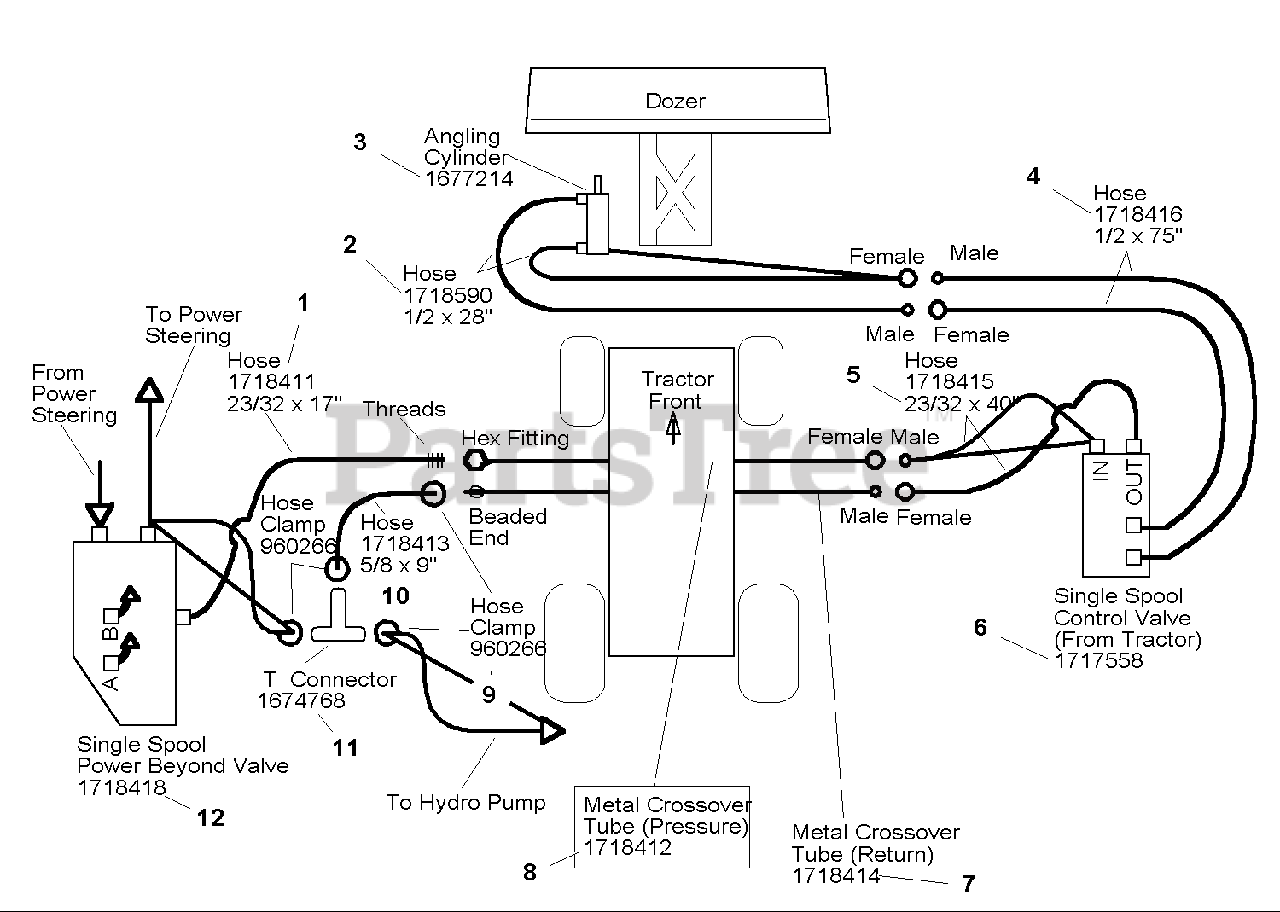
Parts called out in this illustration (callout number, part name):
1	HOSE ASSEMBLY, 23/32" x 17"
2	HOSE, Hydraulic, 1/2" x 28"
3	CYLINDER, Angling
4	HOSE, Hydraulic, 1/2" x 75"
5	HOSE, Hydraulic, 23/32" x 40"
6	CONTROL VALVE, Single Spool (From Tractor)
7	TUBE, Metal Cross-Over (Return)
8	TUBE, Metal Cross-Over (Pressure)
9	CLAMP, Hose, Worm
10	HOSE, Hydraulic 3/8" ID x 9"
11	FITTING, Hose, Tee
12	CONTROL VALVE, Single Spool, Power Beyond
